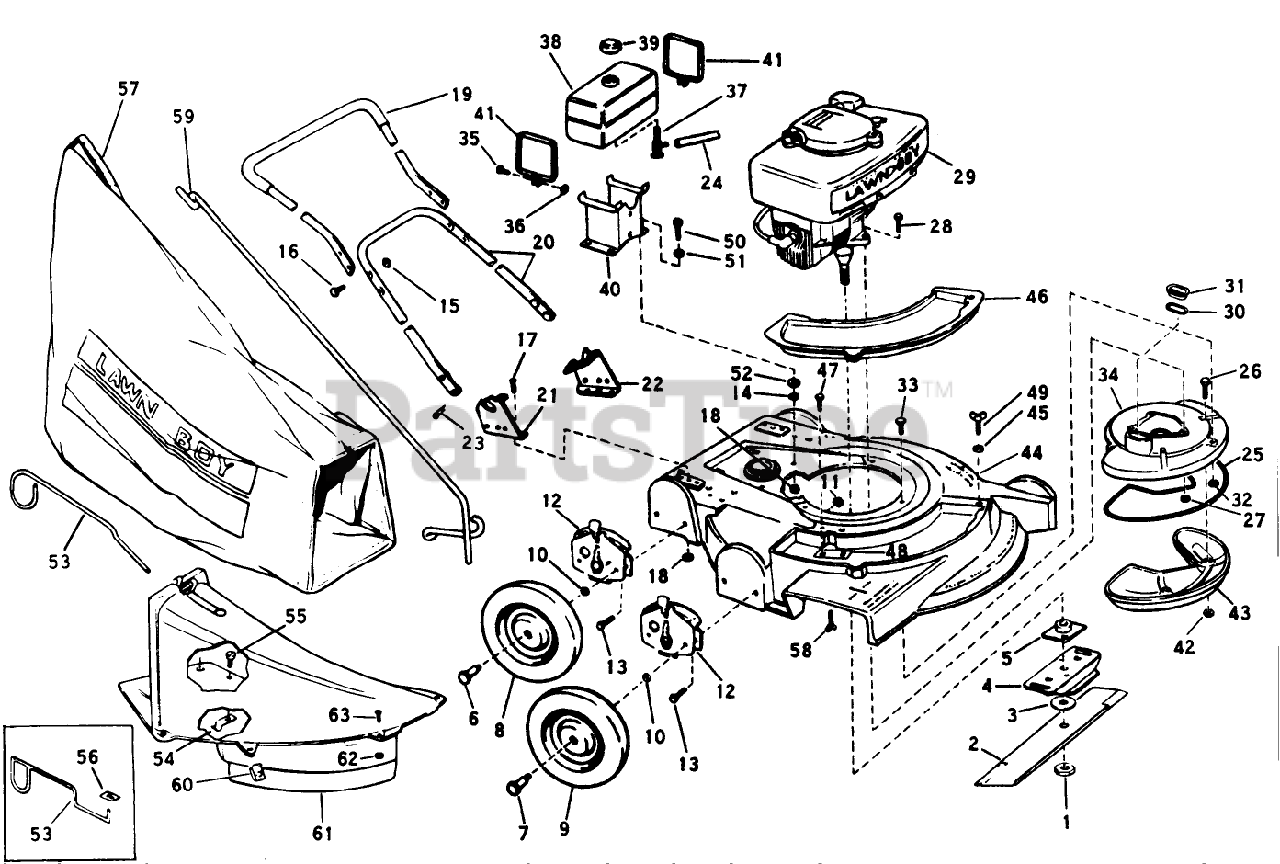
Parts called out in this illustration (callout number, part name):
1	NUT-BLADE
5	PLATE AND COLLAR ASM
6	BOLT-SHOULDER
7	BOLT WHEEL
10	WASHER WROUGHT
15	STOP NUT
17	SCREW S
19	Handle Grip Assy. Top
30	GASKET S
37	VALVE&SCREEN SM
42	LOCKNUT E
57	89802 LB WHOLE GOODS
60	SPEED NUT ARDEN
61	Chute Skirt Assembly (Includes Hardware)
